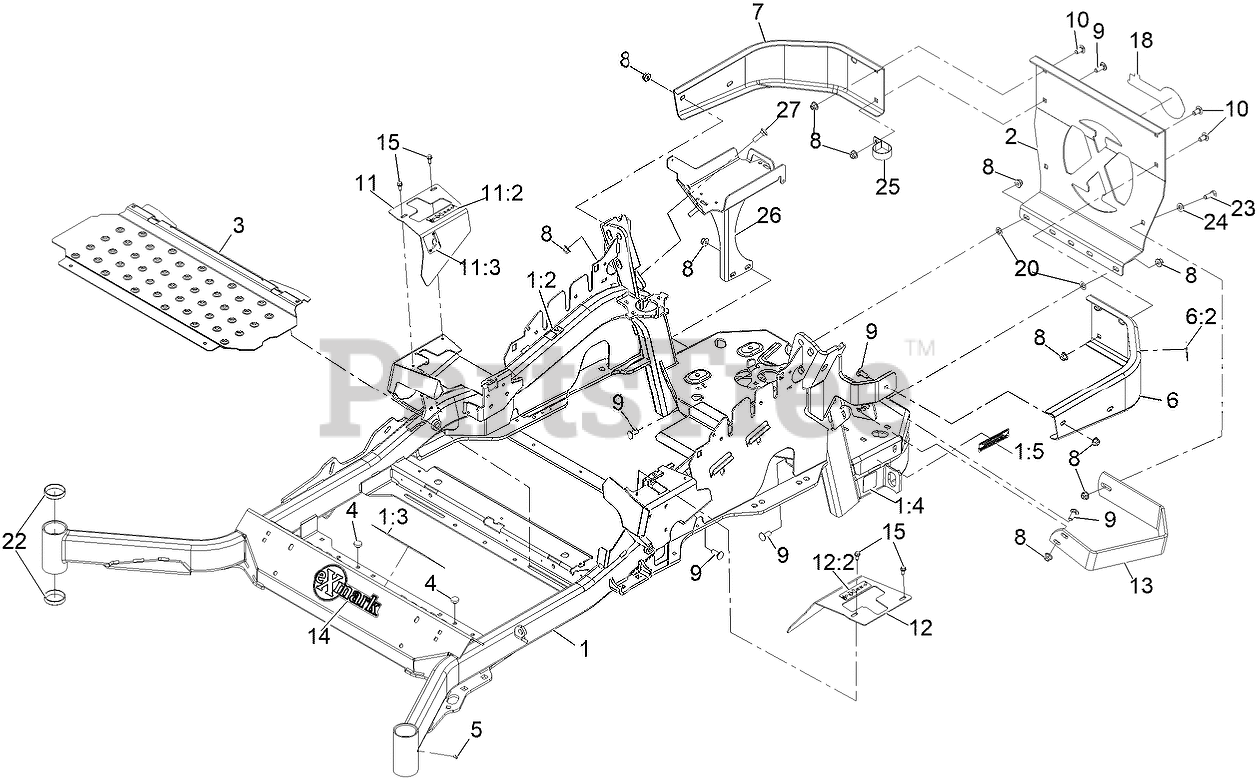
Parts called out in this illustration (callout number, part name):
1	MAINFRAME SERVICE ASM - 72
1:2	DECAL-WARNING
1:3	DECAL-DANGER
1:4	DECAL-HAZARD, PINCHED FINGER
1:5	DECAL-ARRESTOR, SPARK
2	PLATE,REAR GUARD
6	LH BUMPER ASM
6:2	DECAL-WARNING
7	BUMPER-RH
8	NUT-HF, NI
9	SCREW-CARR
10	SCREW-CARR
11	RH MOTION CONTROL COVER ASM
11:2	DECAL-CONTROL, MOTION
11:3	DECAL-PARK BRAKE, CE
12	LH MOTION CONTROL COVER ASM
12:2	DECAL-CONTROL, MOTION
13	GUARD-MUFFLER
14	DECAL-EXMARK
15	SCREW-HWH
18	DECAL, EXMARK LOGO
20	NUT-PUSH
22	CUP-BEARING
23	SCREW-HH
24	WASHER-FLAT
25	CLAMP-R
26	BATTERY MOUNT ASM
27	BOLT-CARR
